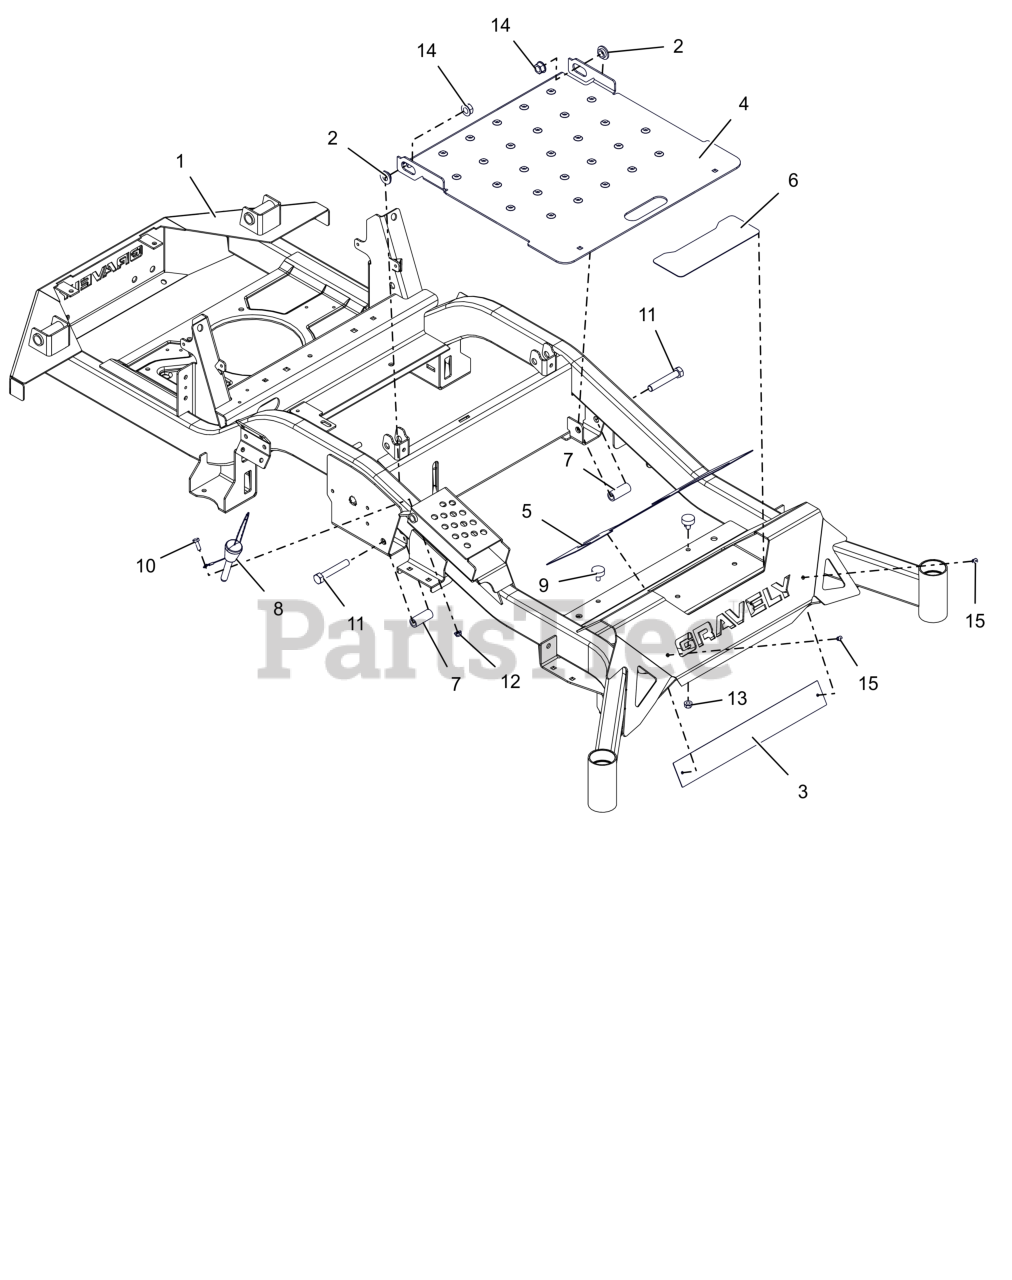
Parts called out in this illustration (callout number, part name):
1	HD 60"FRAME W/SAFETY DECALS
2	BSHG-FLG .515X.750X.310X1.120
3	PLATE, BACK FOOT-REST XL
4	KIT,ACCESS PANEL W/DECALS-RED
5	GRIP, FRONT
6	GRIP, STEP
7	SPACER, .515X.75X1.83
8	PIN, MAGNETIC .50X2.50
9	BUMPER, RUBBER
10	BLT, HEX .25-20X.75 G5 ZCC
11	BLT, HEX .50-13X3.00 G5 ZCC
12	NUT,NYL-FLG .25-20 GF ZCC
13	NUT,SPNLK-FLG .31-18 G5 ZCC
14	NUT-LK-TOP-FLG .500-13 GF ZCC
15	RIVET, .1875 AL/AL .126-.250
